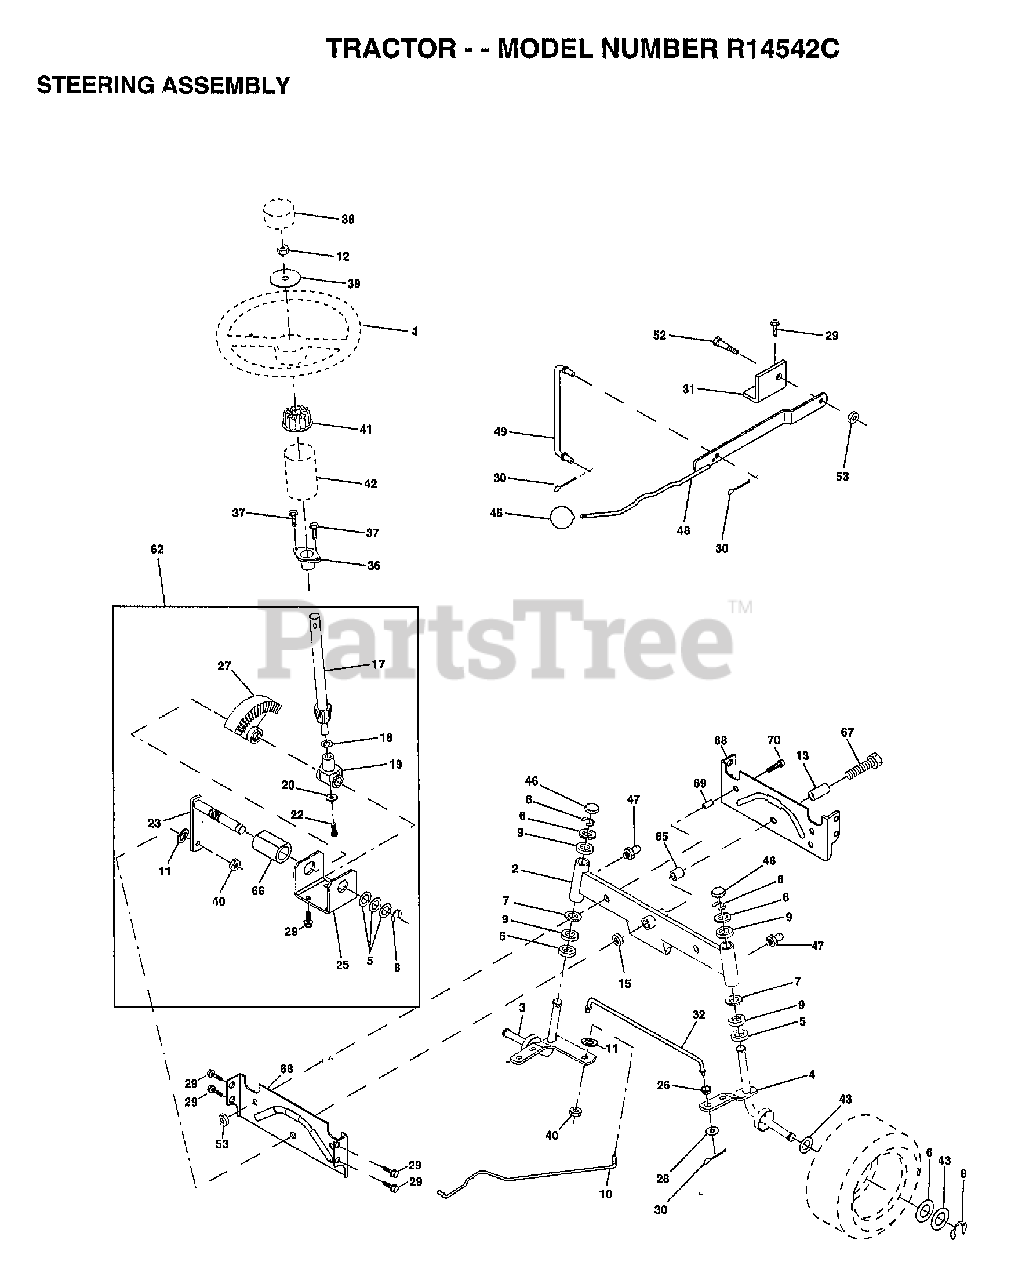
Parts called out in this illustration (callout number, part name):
2	AXLE ASM
3	SPINDLE.ASM.LH
4	"SPINDLE ASM,RH"
5	WASHER .T
6	WASHER
7	WASHER
9	COL. SRTG. BEAR.
10	DRAGLINK-STAMPED
11	LOCKWASHER
13	BEARING AXLE
15	"NUT-LOC,FLANGE LT"
17	SHAFT ASM STEERNG
18	THRUST WASHER
19	SUPPORT.SHAFT
22	SCREW HEX SOC1/4-
25	BRKT-STEERING
26	BUSHING.DRAGLINK
27	GEAR SECTOR
28	WASHER
29	SCREW
30	COTTER PIN
31	BRKT.PVT.MAN.LVR.
32	TIE ROD
36	BUSHING.STRG.3/4
37	"SCREW-TT,10-32 FL"
38	ST WHL INSERT CAP
39	WASHER
40	GRIPCO NUT
41	ADAPTER LT
42	BOOT SHAFT STEER
43	WASHER
45	KNOB T (1/2-HOLE)
46	CAP
47	ZERK M
48	LEVER.ASM.CLUTCH
49	LINK CLTCH W/NUTS
52	"BOLT, SHOULDER LT"
62	KIT STEERING ASM
65	SPACER AXLE
66	"BEARING-ARM,PITMA"
67	BOLT
68	BRACE AXLE
69	"SPACER BRCAE,AXLE"
70	BOLT.HEX.3/8-16X2
